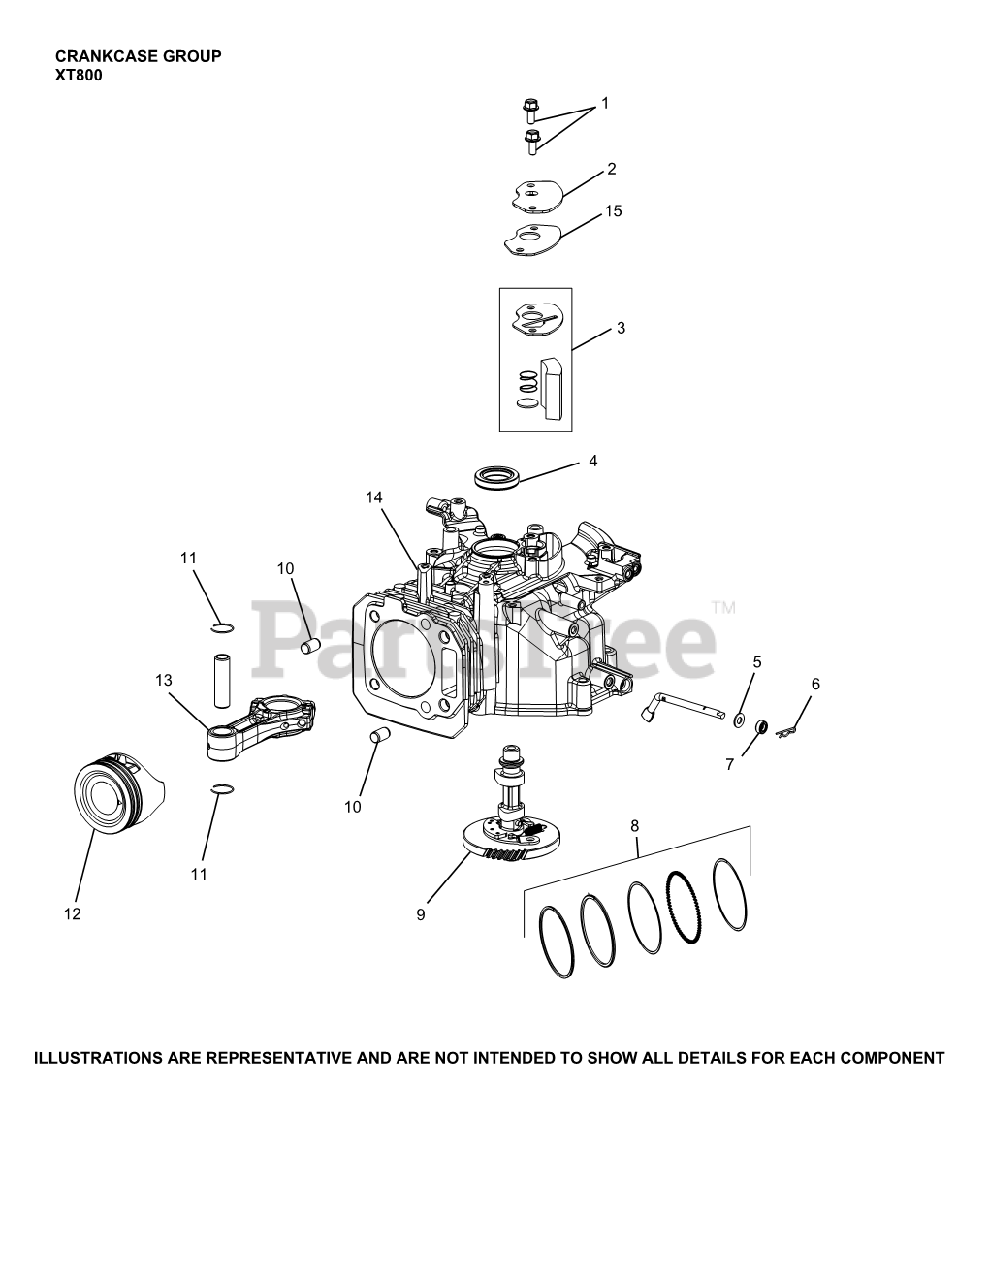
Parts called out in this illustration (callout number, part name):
1	SCREW, HEX FLANGE (M6)-USE 25 086 433-S
2	COVER, BREATHER
3	KIT, BREATHER FILTER
4	SEAL, CCASE/FLYWHEEL
5	WASHER, FLAT (DIA 13MM O.D.)
6	CLIP, GOVERNOR SHAFT
7	SEAL, OIL
9	CAMSHAFT ASSEMBLY
10	DOWEL, CYLINDER HEAD-(#1438013S)
11	RETAINER, PISTON PIN
12	KIT, PISTON
13	CONNECTING ROD
14	CRANKCASE
15	GASKET, BREATHER COVER
